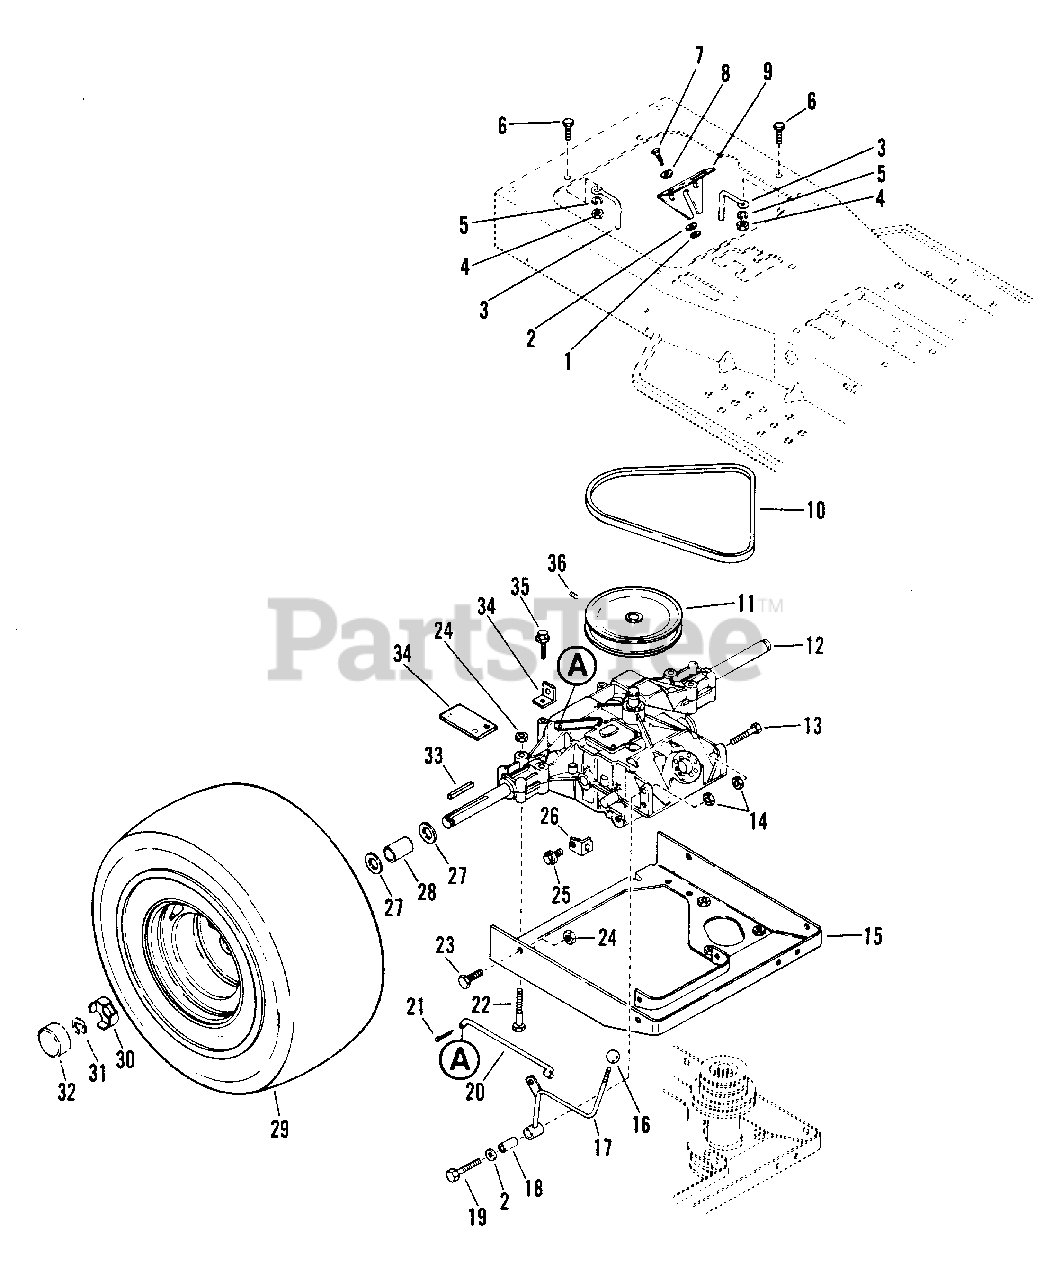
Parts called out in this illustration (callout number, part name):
1	NUT, LOCK 5/16-18
2	WASHER, FLAT .312X.734X.065
3	FINGER, BELT
4	NUT, HEX 3/8-16
5	WASHER, LOCK 3/8 REG.
6	BOLT, HEX 3/8-16X1.25
7	BOLT, HEX 5/16-18X.875
8	SPACER
9	ACTUATOR, CAM
10	BELT, TRACTION
11	SHEAVE, TRANSAXLE
12	ASSEMBLY, TRANSMISSION
13	BOLT, HEX 1/4-20X1.00
14	NUT, LOCK 1/4-20
15	MOUNT, TRANSMISSION
16	KNOB, ADJUSTMENT CONTROL
17	LEVER, RANGE SELECTOR
18	SPACER
19	BOLT, HEX 1/4-20X2.00
20	ROD, SELECTOR
21	PIN, COTTER .094X.75
22	BOLT, HEX 3/8-16X2.75
23	BOLT, HEX 3/8-16X1.00
24	NUT, LOCK 3/8-16
25	BOLT, HEX 5/16-18X.50
26	ANCHOR, SPRING
27	WASHER, FLAT .813X1.37X1.00
28	SPACER
28	SPACER, AXLE R.H.
28	SPACER, AXLE L.H.
29	ASSEMBLY, WHEEL AND TIRE
29	TIRE, 18X8.50-8
29	RIM
30	CUP, SPINDLE
31	E-RING
31	SNAP RING
32	CAP, HUB
33	KEY, STRAIGHT .187X2.00X.187
34	PLATE, ANCHOR
35	SCREW, TAPTITE
36	SCREW, SET 1/4-20X.375 HSCP
